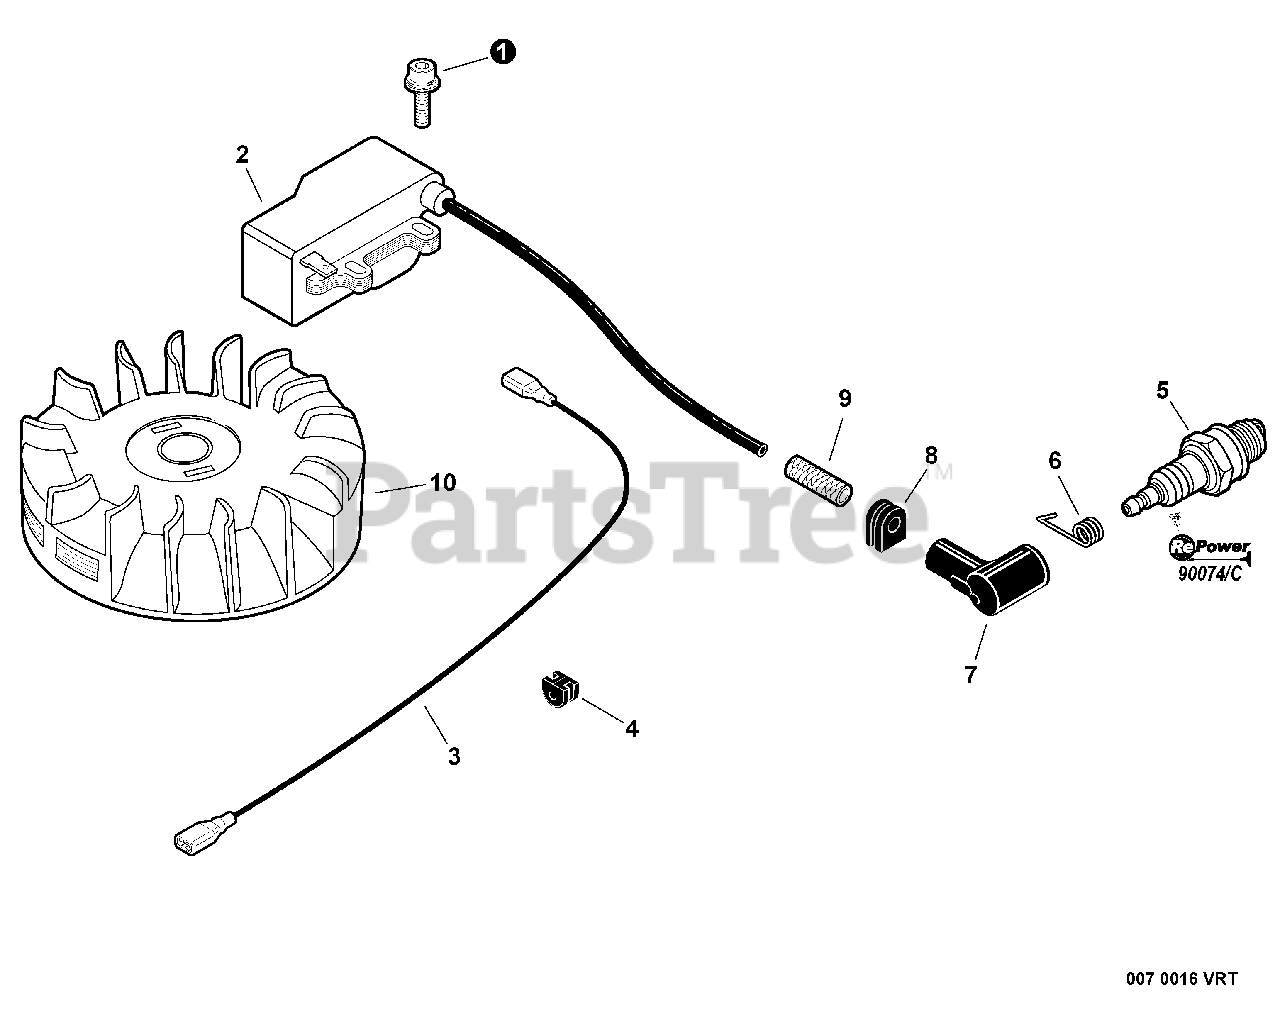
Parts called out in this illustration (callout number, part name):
1	BOLT 4×20
2	COIL, IGNITION
3	LEAD
5	SPARK PLUG - BPM8Y
5	SPARK PLUG - BPMR8Y
6	TERMINAL, SPARK PLUG
7	CAP, SPARK PLUG
9	TUBE, INSULATOR
10	FLYWHEEL
11	TUNE-UP KIT - REPOWER
